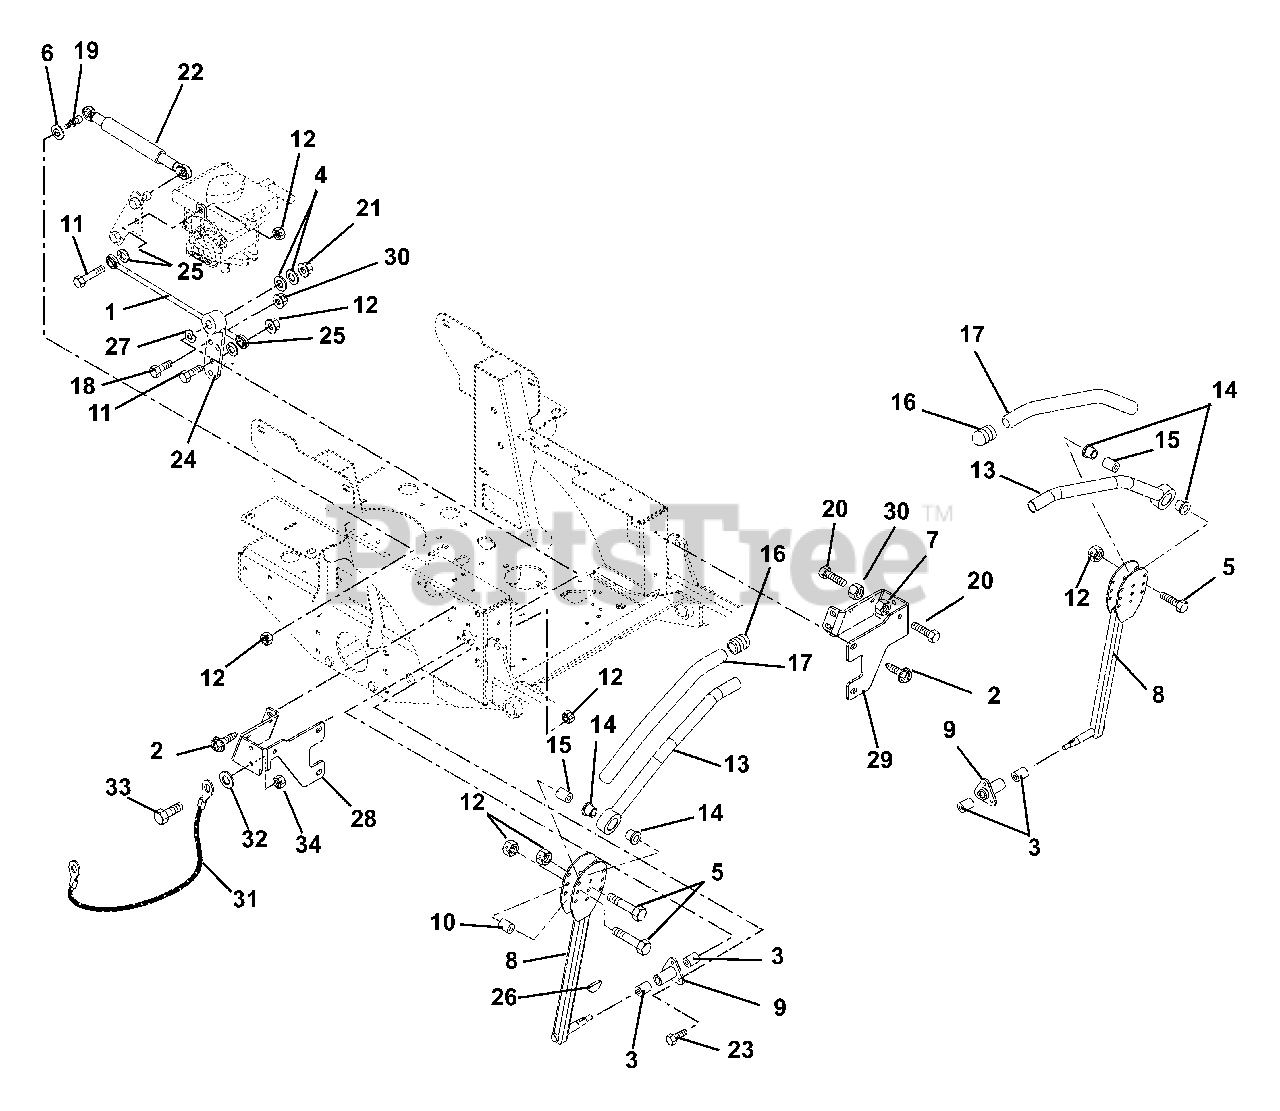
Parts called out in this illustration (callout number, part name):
1	Assembly, Steering Rod
2	Screw, Tapping .38-16 x .75 Hex Washer Head
3	Bushing .625 x .75 x .50
4	Washer, Flat Steel .406 x .812 x .065
5	Bolt, Hex .31-18 x 1.75 Grade 5
6	Washer, Flat Steel .344 x .688 x .065
7	Nut, Hex Jam .375-16
8	Control Arm
9	Housing, Bushing
10	Eccentric
11	Bolt, Hex .31-18 x 1.25 Grade 5
12	Nut, Locking Top Flange .31-18
13	Handle Weldment Left-Hand
13	Handle Weldment Right-Hand
14	Bushing, Flange Nylon .762 x 1.48 x .44
16	Caplug, Handlebar
17	Grip, Handlebar
18	Bolt, Hex .375-16 x 1.75
19	Stud, Ball
20	Bolt, Hex .38-16 x 1.25 Grade 5
21	Nut, Locking Top Flange .38-16
22	Dampener, Control
23	Bolt, Hex .31-18 x .75 Grade 5
24	Weldment, Pivot Arm
25	Washer, Locking .31 x .078 Regular
26	Key, Woodruff .13 x .63
27	Wave Washer
28	Stop, Steering-Right Hand
29	Stop, Steering-Left Hand
30	Nut, Locking Jam Center .375-16
31	Cable, Hood
32	Washer, Flat Steel .265 x .50 x .087
33	Bolt-Hex .25-20 x .75 Grade 5
34	Nut, Locking Top Flange .25-20
